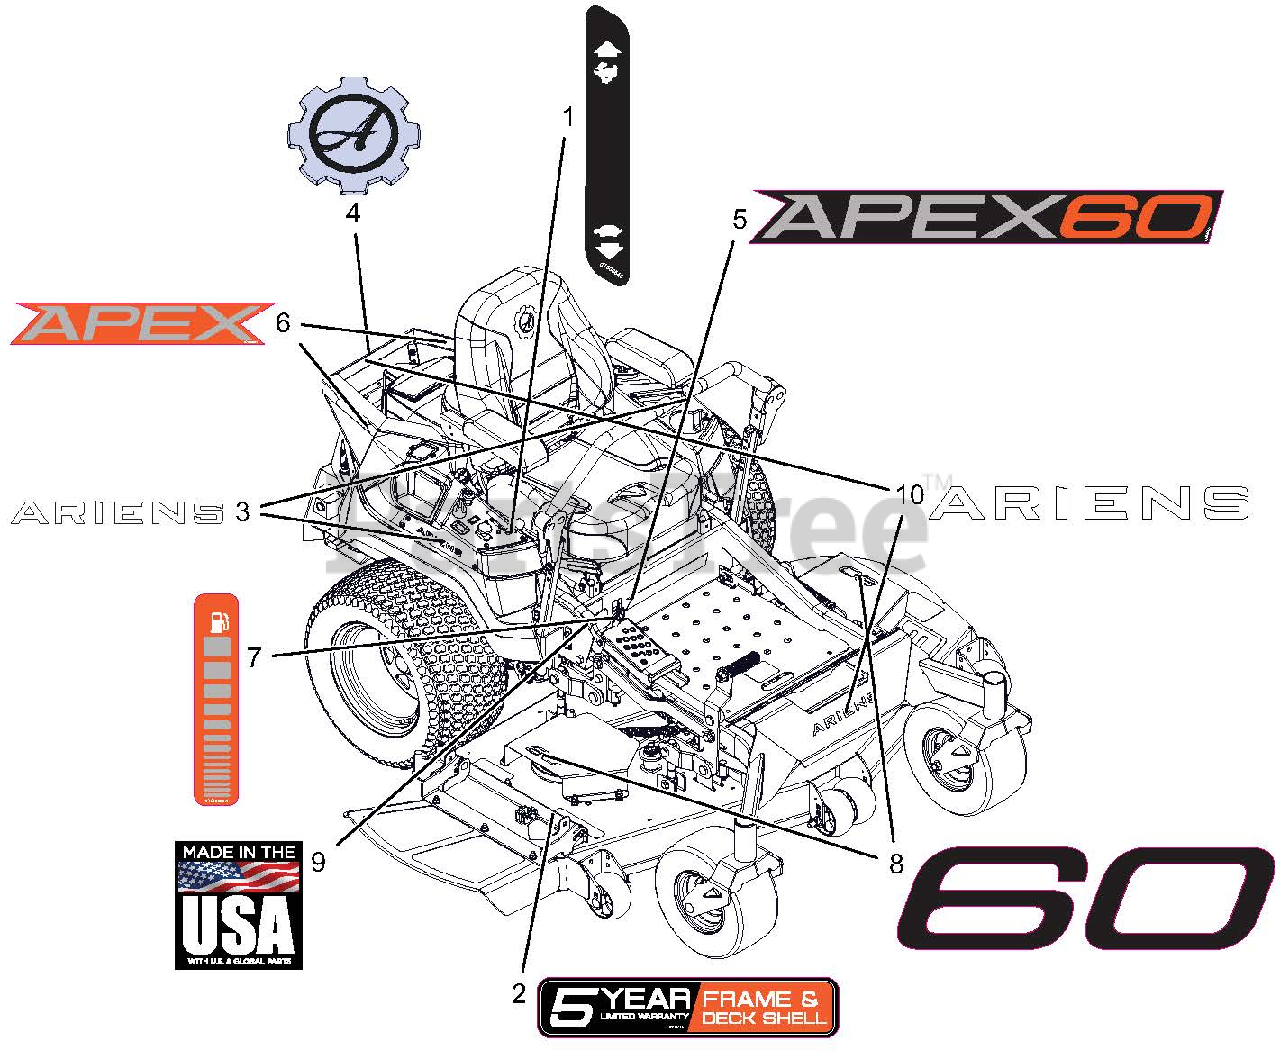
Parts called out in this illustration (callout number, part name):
1	DECAL, DASH DECAL
2	DECAL, DECK 5 YEAR-ARIENS
3	DECAL, ARIENS (6.50")
4	DECAL, ARIENS-GEAR BADGE -THK
5	DECAL, 60" APEX KICKPLATE
6	DECAL, APEX FENDER
7	DECAL, ARIENS FUEL LEVEL
8	DECAL, BLACK 60
9	DECAL, MADE IN USA
10	DECAL - ARIENS 9.625"
